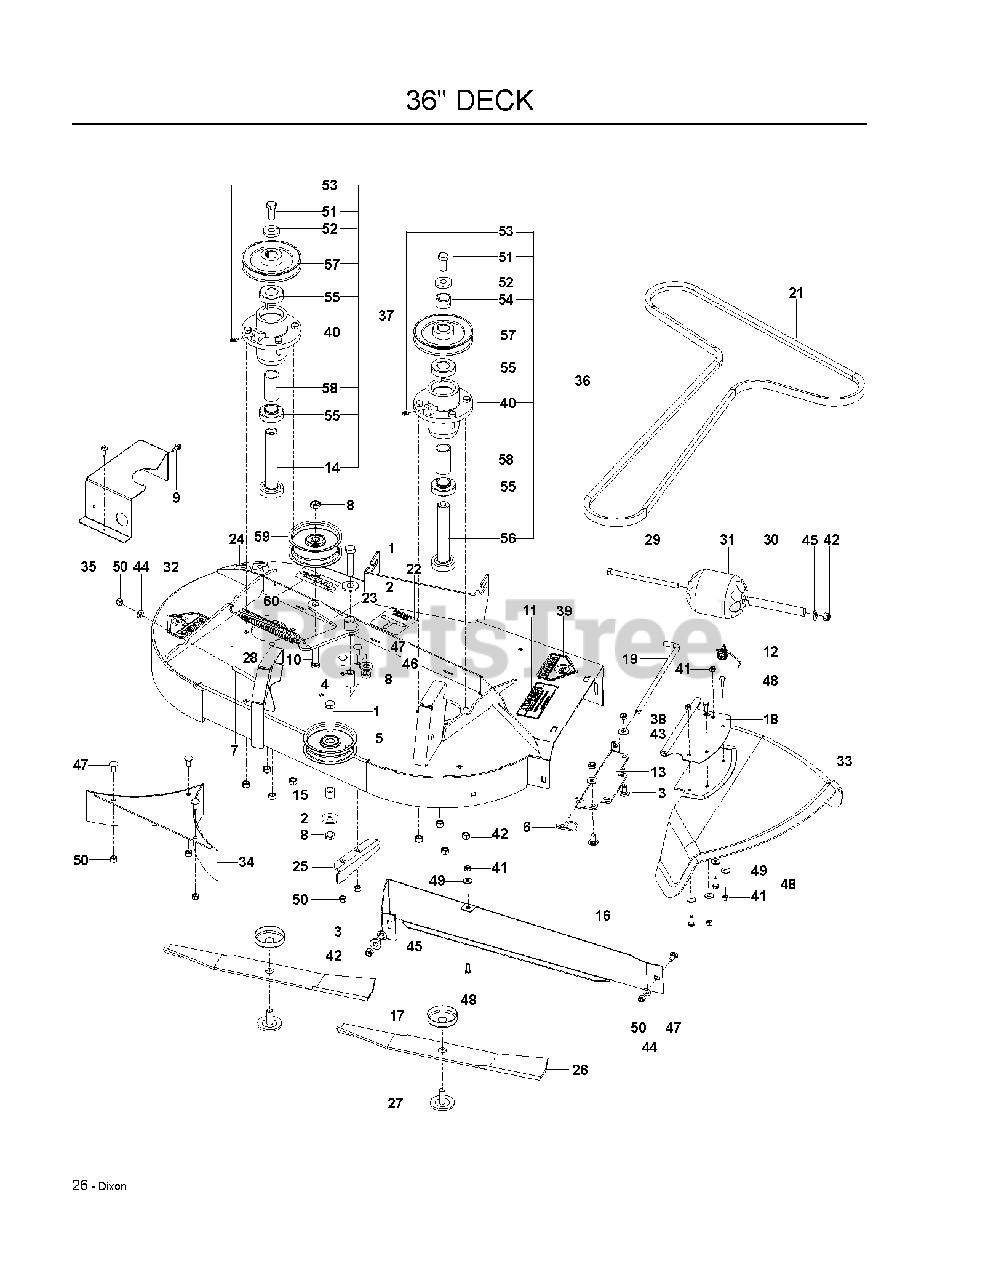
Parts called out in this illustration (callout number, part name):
1	HEX SCREW 1/2-13 X 2.5" GR 5
2	WASH USS FLAT 1/2
3	RHSNB 3/8-16 X 3/4 GR5 ZD
4	BUSHING DIXON 1080
5	PULLEY IDLER
6	PIN, COTTER 1 3/4
7	EYE BOLT 5/16 X 3.50
8	NUT, 1/2-13 THIN PROF NYL
9	SCREW, TAP & DR #12-14 X 3/4
10	STUD 1/2-13 X 2
11	DECAL, DANGER
12	SPRING, TORSION
14	SHAFT 50S
15	BUSHING
17	TRASH GUARD
18	DEFLECTOR MT BRKT
19	DEFLECTOR PIN
20	OUTER SHAFT KEY
22	DECAL, BELT ROUTING
23	IDLER ARM WLDT., BLACK
24	DECAL, DECK 36"
25	BAFFLE DECK
26	BLD 36" HI LIFT FUS
27	BLADE BOLT
28	SPRING, DECK BELT
29	BOLT 3/8 X 6 GR5
30	BUSHING
31	ROLLER 3-3/4 DIA. X 4-1
32	DECK W/DECALS - SZ36
33	PLASTIC DEFLECTOR 36
34	BAFFLE WLDT
35	PULLEY GUARD
36	HUB ASM RH
37	HUB ASM LH
38	NUT HEX 3/8-16 NYLON, THIN
39	DECAL, CPSC
40	HCS 3/8C X 1 1/4 GR5
41	NUT 1/4-20 NYLOC
42	NUT 3/8-16 NYLOC
43	WASHER 5/16 FLAT
44	FLAT WASHER 5/16 SAE
45	WASHER 3/8 FLAT
46	WASHER 1/2" FLAT
47	BOLT 5/16C X 3/4" CARRIAGE
48	HCS 1/4C X 3/4 HCS
49	WASHER 1/4 FLAT
50	NUT 5/16 NYLOC
51	1/2-20 UNF X 1 1/4 HHBLT
52	WASHER .525 X 1.375 X .25
53	ZERK, 3/16, DRIVE IN
54	SPACER HUB
55	BEARING-ECC LOCK
57	PULLEY 5``B`
59	IDLER PULLEY
60	DECAL, FUSION
